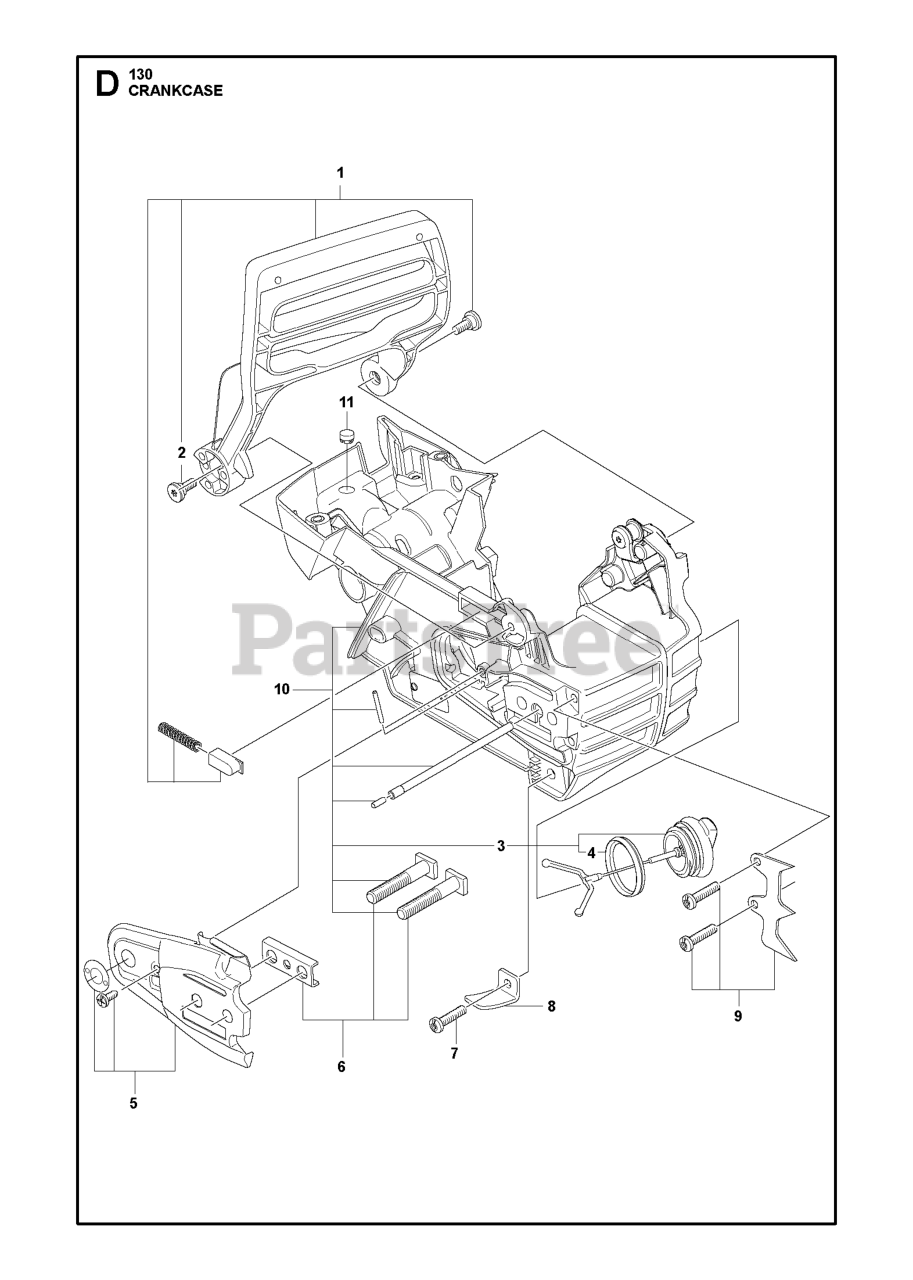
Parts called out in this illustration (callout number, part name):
1	SERVICE KIT HAND GUARD
2	BOSS SCREW
3	ASSY TANK CAP GREY
5	SERVICE KIT BAR PLATE
6	SERVICE KIT BAR BOLT
7	SCREW M5.38-14X22.225MM
8	CHAIN CATCHER 36/41
9	SPIKE 36/41
10	SERVICE KIT CHASSIS
